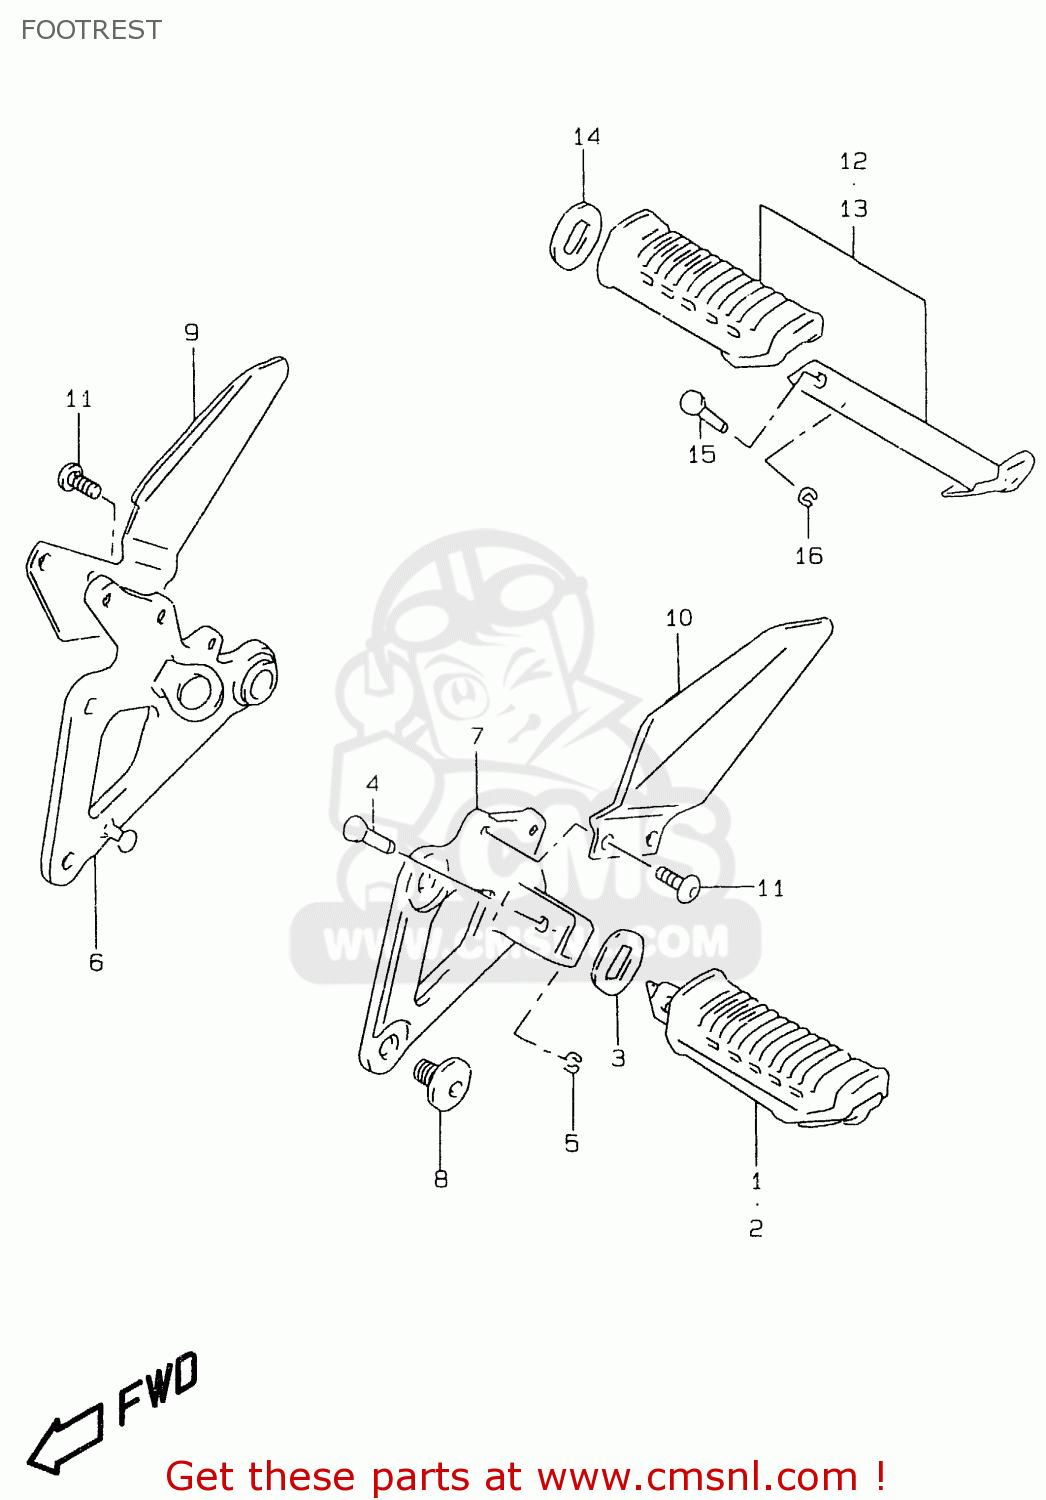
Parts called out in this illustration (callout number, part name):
1	RUBBER,FR FOOTREST,R
2	RUBBER,FR FOOTREST,L
3	WASHER,FOOTREST RUBBER
4	PIN
5	E-RING
6	BRACKET,FR FOOTREST,R
7	BRACKET,FR FOOTREST,L
8	BOLT(8X20)
9	GUARD,FR FOOTREST,R
10	GUARD,FR FOOTREST,L
11	SCREW(6X12)
12	FOOTREST ASSY,PILLION,R
13	FOOTREST ASSY,PILLION,L
14	WASHER,FOOTREST RUBBER
15	PIN
16	E-RING
